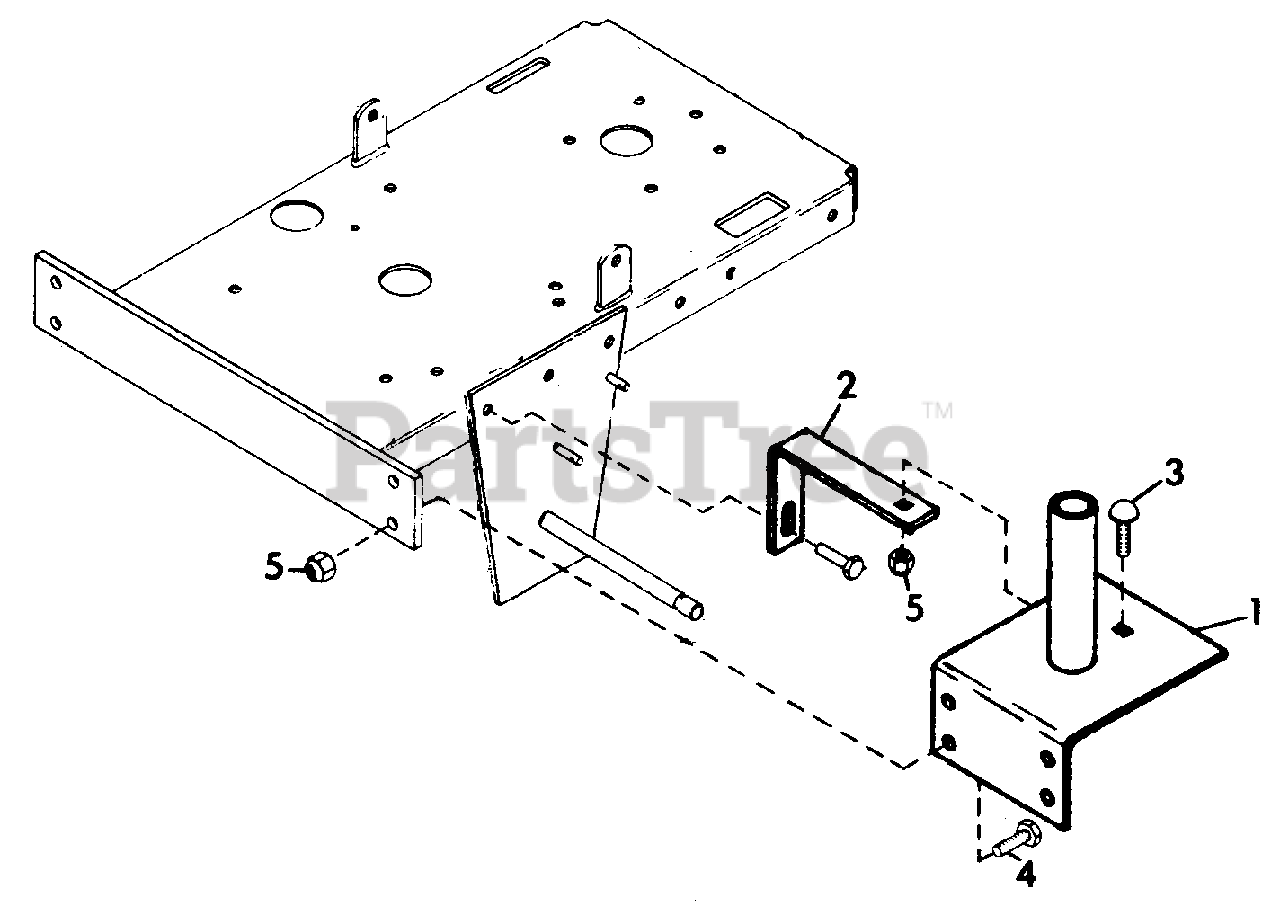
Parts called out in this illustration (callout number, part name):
1	WELDMENT, SUPPORT
2	BRACE, SUPPORT
3	BOLT, 1/2-13 X 1.50 RD HD SQ NK
4	BOLT, HEX 1/2-13 X 1.75
5	NUT, LOCK 1/2-13
